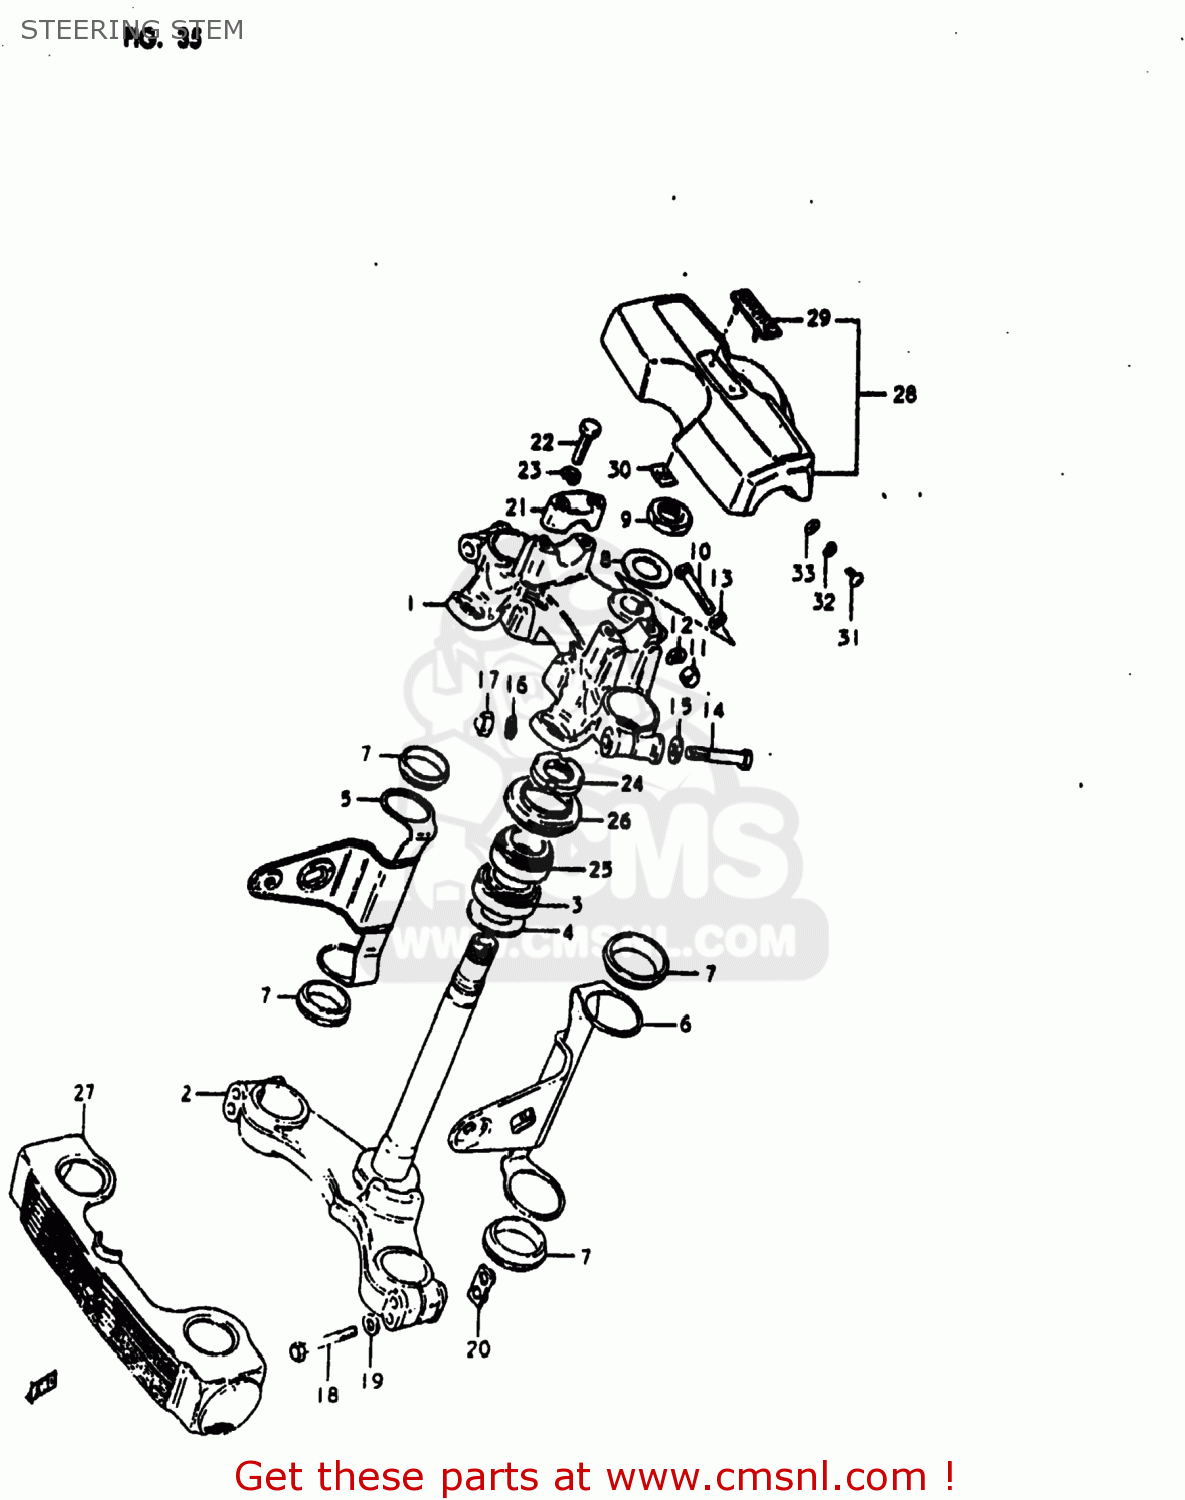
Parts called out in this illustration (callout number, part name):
1	HEAD,STEERING STEM
2	STEM,STEERING
3	BEARING
4	WASHER,THRUST
5	BRACKET,HEADLAMP,RIGHT
6	BRACKET,HEADLAMP,LEFT
7	CUSHION,HEADLAMP BRACKET
8	WASHER
9	NUT,FR FORK UPR BRACKET
10	BOLT 8X50
11	NUT
12	LOCK WASHER
13	WASHER
14	BOLT 10X55
15	WASHER
16	LOCK WASHER
17	NUT, LOWER LH
18	BOLT 8X55
19	WASHER
20	NUT,FR FORK INNER TUBE
21	HOLDER,HANDLE(BLACK)
22	BOLT
23	LOCK WASHER
24	NUT,STEERING STEM(25X44X10)
25	TAPER,ROLLER BEARING
26	DUST SEAL,STEERING,UPPER
27	COVER,FRONT FORK
28	PAD,HANDLEBAR
29	EMBLEM,HANDLE COVER PAD
30	NUT
31	SCREW
32	LOCK WASHER
33	WASHER
